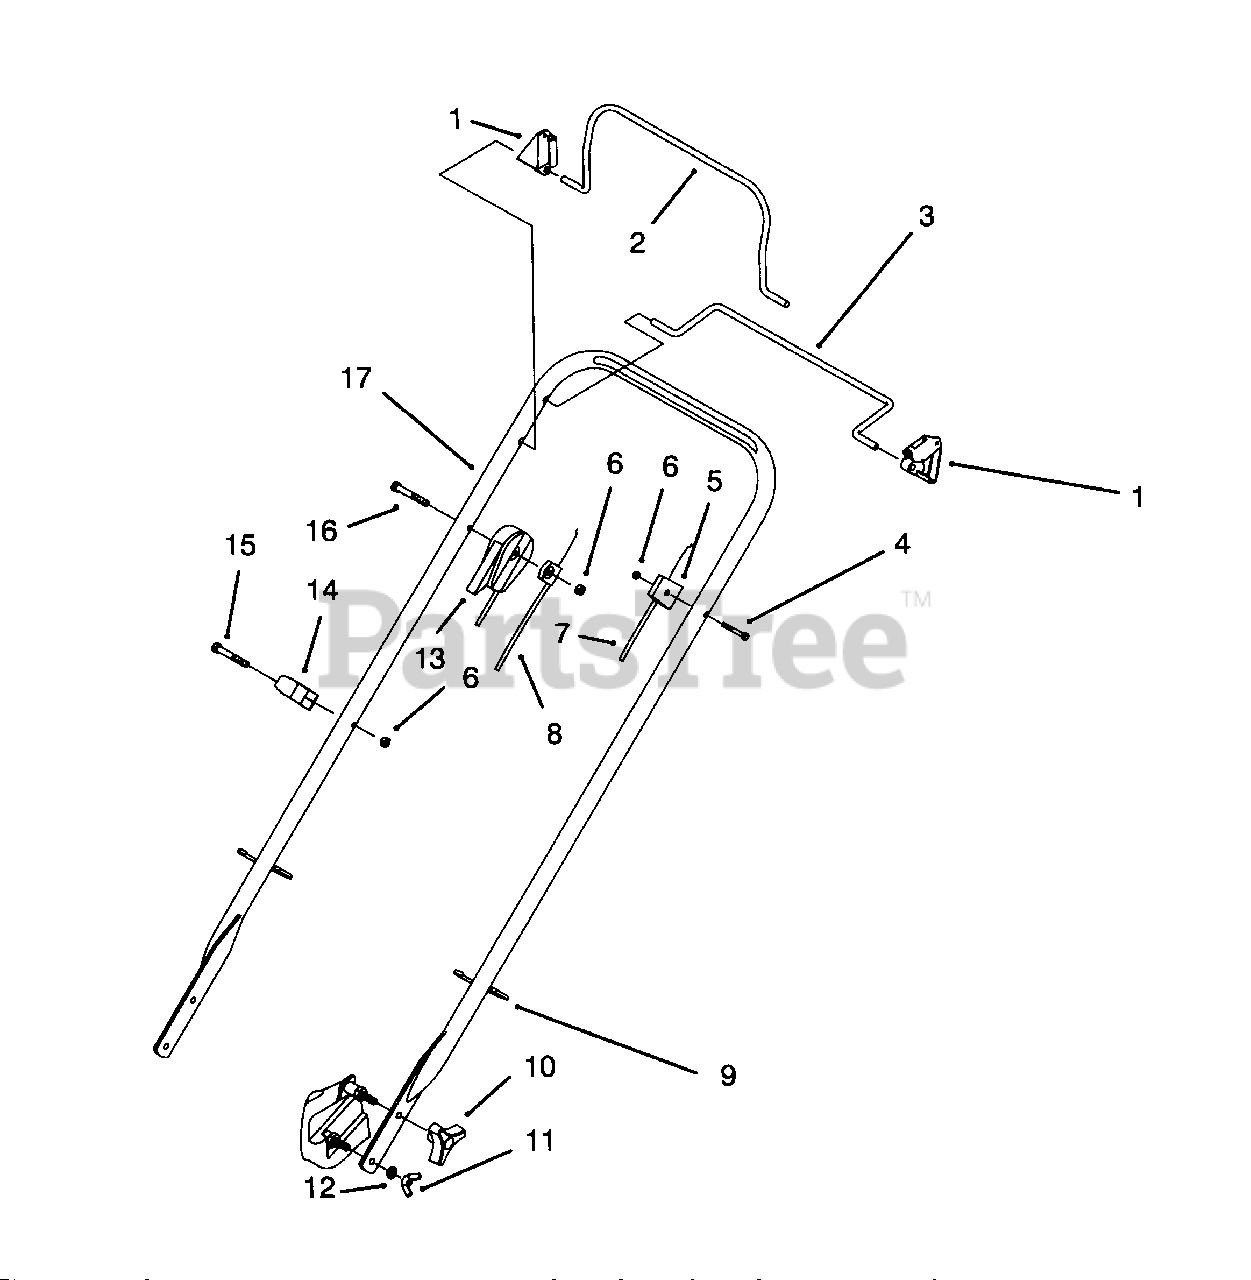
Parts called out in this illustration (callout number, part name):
1	Stop-Pivot
2	Bail-Flywheel Brake
3	Bail-S.P Control
4	Screw-Hex Hd. Screw
5	Anchor-Cable S.P Upper
6	Nut-Lock
7	Cable-Traction
8	Cable-Flywheel Brake
9	Tie-Cable
10	Knob
12	Washer-Lock
13	Cable-Throttle
14	Guide-Rope
15	Screw-Hex Hd. Cap
16	Screw-HEX Hd. Cap
